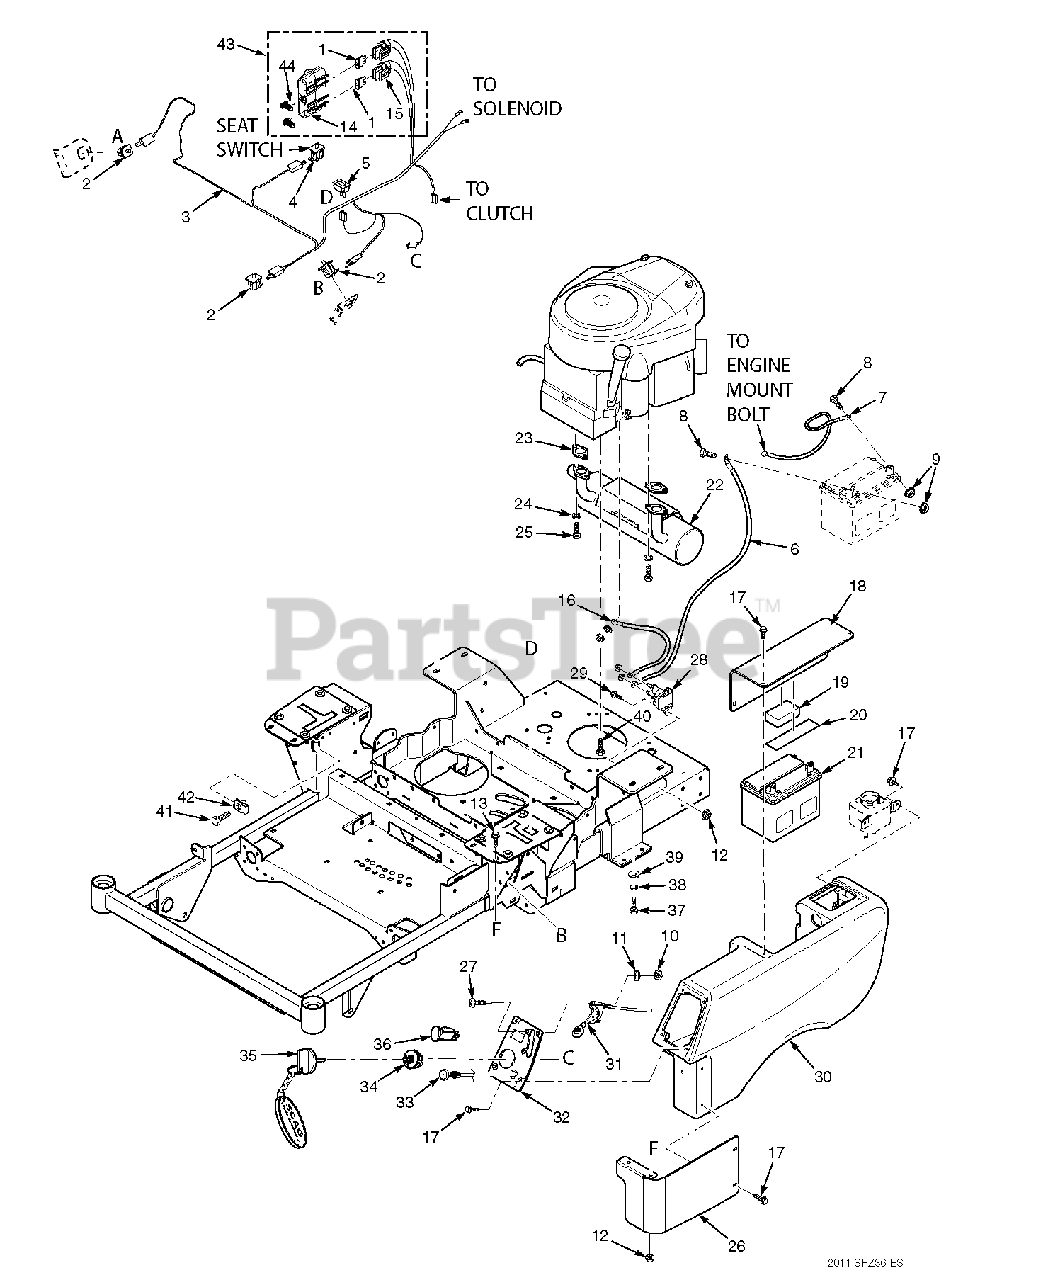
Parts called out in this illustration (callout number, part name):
1	Fuse, 20 amp
2	Switch
3	Wire Harness, Main
4	Switch, Seat
5	Hourmeter
6	Battery Cable, Red 25"
7	Battery Cable, Black 27"
8	Bolt, Hex Head 1/4-20 x 1/2"
9	Nut, 1/4-20
10	Nut, Hex #10-32
11	Lockwasher, #10 External Tooth
12	Nut, Serrated Flange 1/4-20
13	Bolt, Hex Head 1/4-20 x 3/4" Serr. Flange
14	Cover, Sealed Double
15	Fuse Holder
16	Battery Cable, Red 9"
17	Bolt, Hex Head 1/4-20 x 1/2" Serr. Flange
18	Battery Cover
19	Pad, Battery Hold Down
20	Rubber Pad
21	Battery
22	Muffler
23	Exhaust Gasket
24	Lockwasher
25	Bolt
26	Control Cover, LH
27	Screw, #10-32 X 3/4"
28	Solenoid
29	Bolt, Hex Head 1/4-20 x 0.63"
30	Tank, LH
31	Throttle Cable
32	Instrument Panel w/Decal
33	Choke Cable
34	Ignition Switch
35	Key, Ignition
36	PTO Switch
37	Bolt, Hex Head 5/16-18 x 3/4"
38	Lockwasher, 5/16" Spring
39	Flatwasher, 5/16-.375 x .875 x .083
40	Bolt, Hex Head 3/8-16 x 1-1/4"
41	Bolt, Hex Head 3/8-16 x 1-1/4" Special Lock
42	U-Nut, 3/8-16
43	Double Fuse Assy.
44	Clip, Wire
